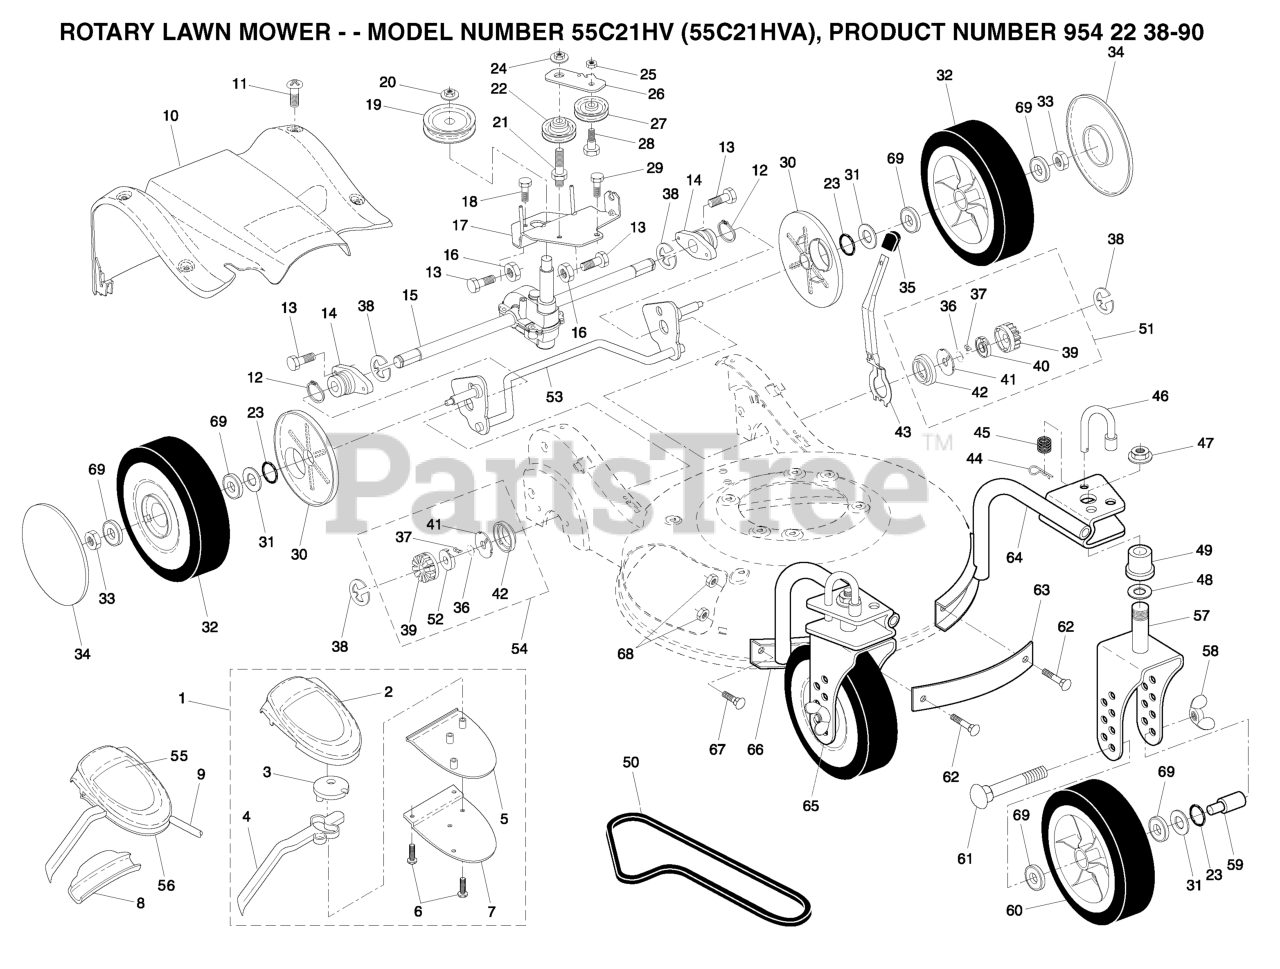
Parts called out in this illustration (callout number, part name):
1	EZ WALK CONTROL
2	COVER, DRIVE CONTROL, TOP
3	PULLEY.CAM.DRIVE.CONTROL.HV
4	LEVER, DRIVE CONTROL
5	COVER, DRIVE CONTROL BOTTOM
6	SCREW, PHILLIPS HEAD 10 X 5/8
7	BRACKET, DRIVE CONTROL
8	EZ WALK SNAP COVER PLATE
9	CABLE, DRIVE CONTROL
10	COVER ASM. DRIVE
11	SCREW
12	RETAINING RING (2 2)(3 2)
13	RP SCREW
14	BEARING.SUPPORT.ASSEM
15	TRANSMISSION.ASM.RGD.EZ.21
16	NUT
17	BRACKET, TRANSMISSION
18	Screw, Hex Washer Head #10-24 x .668
19	PULLEY HALVES
20	FLANGED LOCKNUT 3/8-16 ZINC
21	BOLT, IDLER
22	PULLEY ASSY
23	O-RING
24	NUT
25	NUT.CENTERLOCK.5/16-
26	BRACKET
27	IDLER PULLEY
28	SHOULDER BOLT
29	SCREW 14-20 X 5/8
30	DUST COVER, WHEEL
31	WASHER.FLAT.1/2
32	WHEEL ASM, REAR 9 X 2-1/4
33	HEX FLANGE LOCKNT
34	RB HUBCAP.3-SPOKE.SILVER
35	KNOB.SELECTOR.SPRG.H-GRY (2 2)
36	SPRING, TORSION
37	PAWL.DRIVE.21.EZ-WALK
38	E-RING 7/16 RE
39	GEAR, PINION
40	RETAINER.DRIVE.21.EZ-WALK.LT
41	DISC.DRIVE.21.EZ-WALK
42	SEAL.PINION
43	LEVER, SELECTOR, HEIGHT, REAR
44	COTTER PIN (3 2)(2 2MC)
48	WASHER.FLAT.1/2
50	BELT.DRIVE.EZ.WALK.HI-VAC
51	PINION ASSY, LH
52	RETAINER, DRIVE, RH
53	REAR AXLE ASSY.
54	PINION ASSY, RH
57	BRACKET, CASTER WHEEL, LH
58	NUT.WING.5/16-18.YELLOW
61	CARRIAGE BOLT
63	STRAP.FRONT.CASTER.ORANGE
64	SUPPORT TUBE ASSY, LH
65	BRACKET, CASTER WHEEL, RH
66	SUPPORT TUBE ASSY, RH
68	NUT
69	BEARING.8".WHEEL
